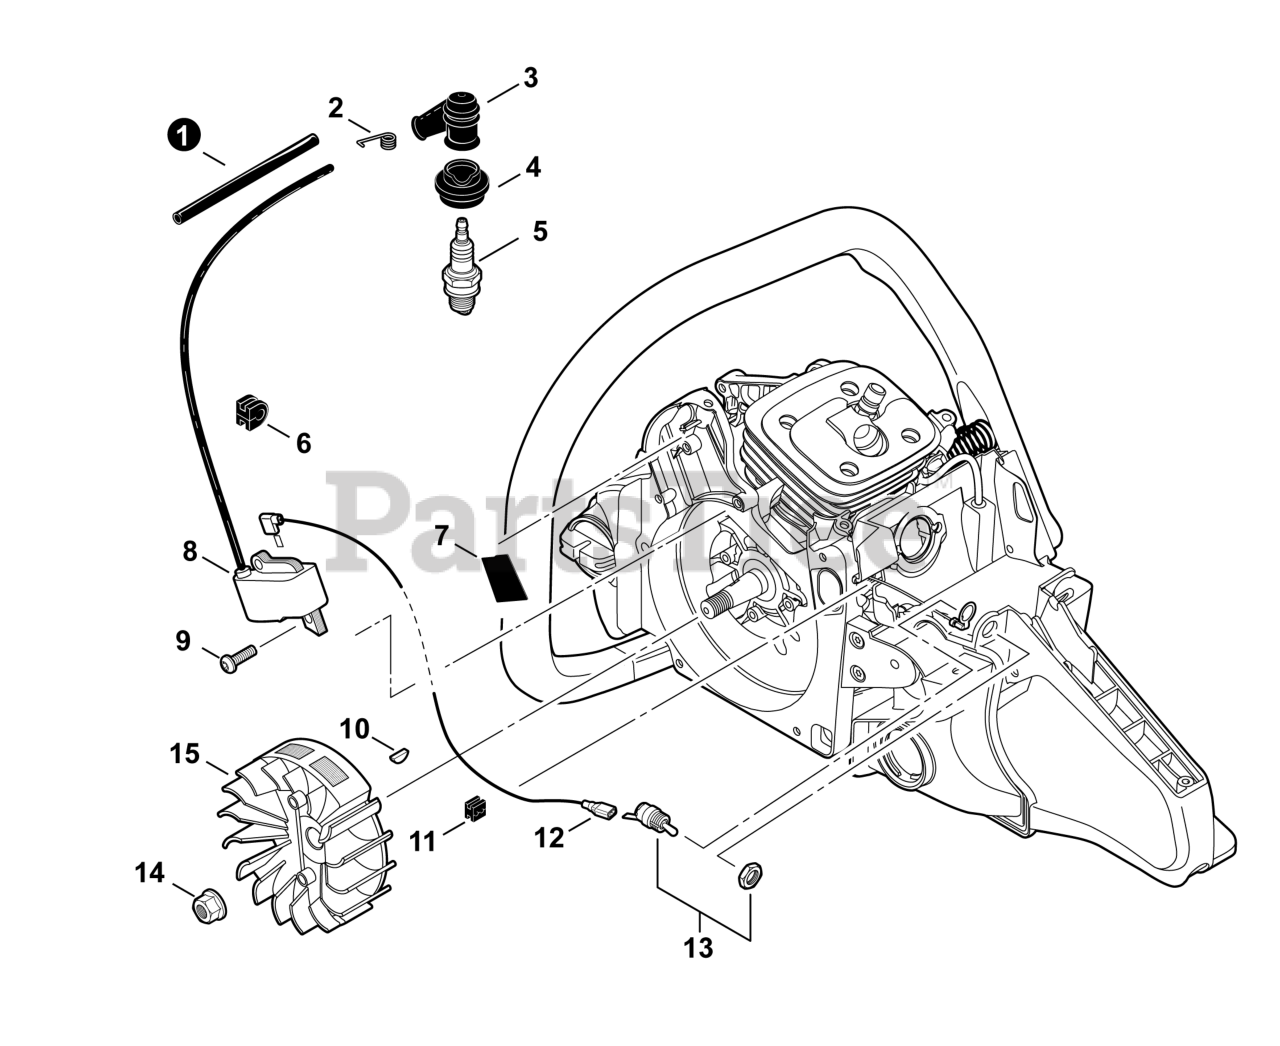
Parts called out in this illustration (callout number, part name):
1	TUBE, IGNITION COIL 6x7.2x70
2	TERMINAL, SPARK PLUG
3	CAP, SPARK PLUG
4	SEAL, SPARK PLUG
5	SPARK PLUG - BPM8Y
7	CUSHION
8	COIL, IGNITION
9	BOLT, TORX 5x16
10	KEY, WOODRUFF
11	GROMMET, LEAD
12	LEAD - IGNITION L= 280
13	SWITCH, ON-OFF
14	NUT, FLANGE M8
15	FLYWHEEL
